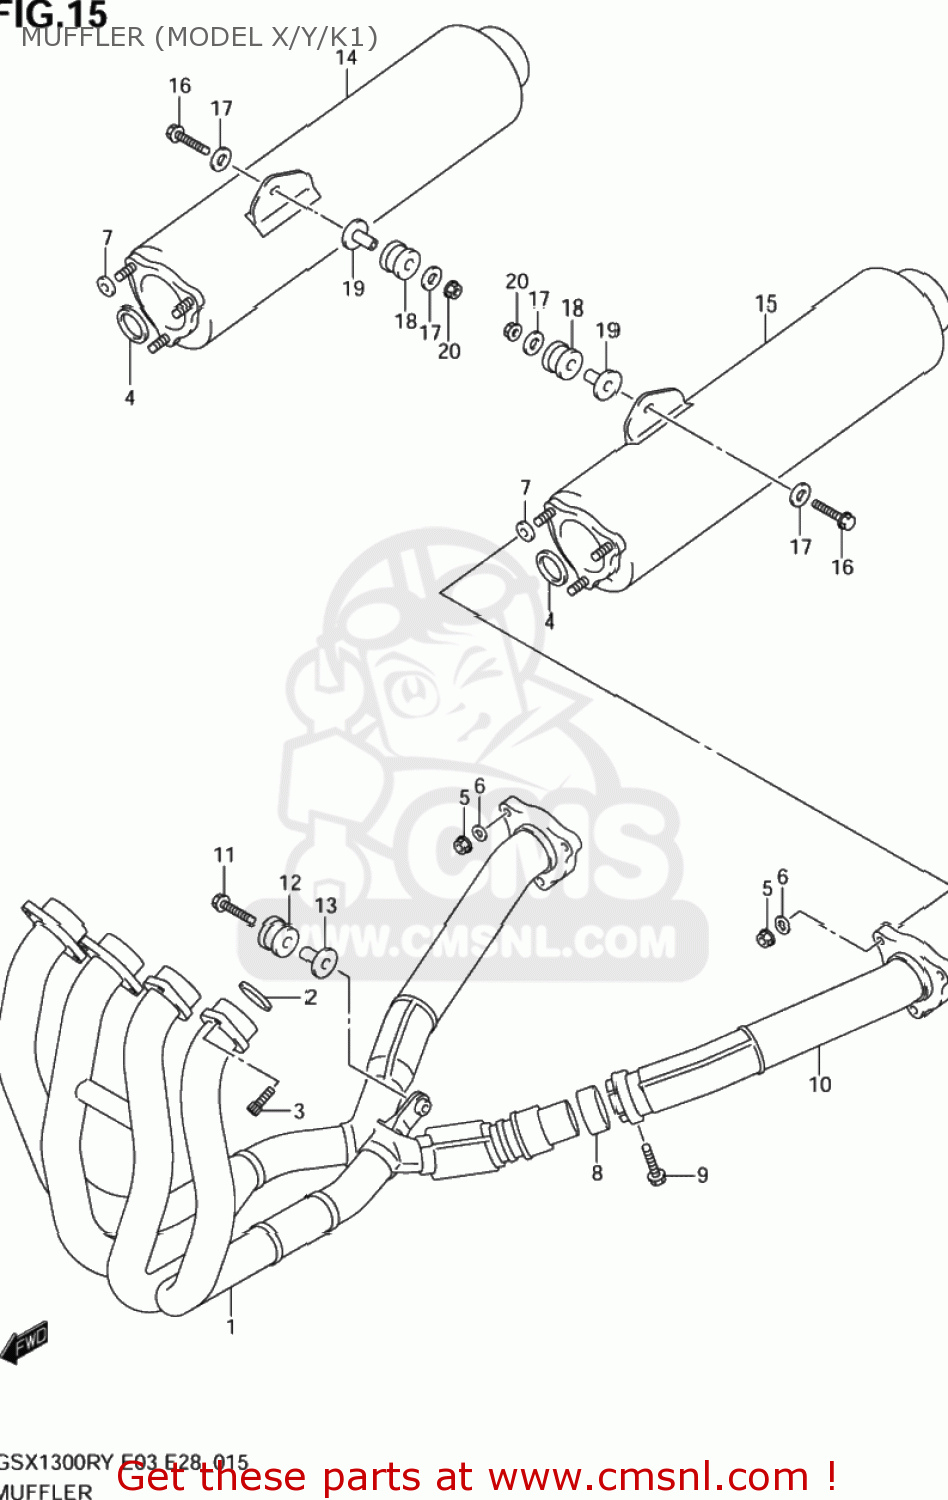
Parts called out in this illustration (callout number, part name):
1	EXHAUST
2	GASKET,EXHAUST PIPE (NAS)
3	BOLT
4	GASKET,MUFFLER JOINT
5	NUT
6	WASHER(8.5X18X1.6)
7	O RING(D:1.9,ID:7.8)
8	CONNECTOR,MUFFLER
9	BOLT
10	PIPE,JOINT,L
11	BOLT 8X45
12	CUSHION
13	SPACER(8.6X12X24.2)
14	BODY,MUFFLER,R
15	BODY,MUFFLER,L
16	BOLT
17	WASHER(8.5X28X1.6)
18	CUSHION
19	SPACER(8.6X12X27.1)
20	NUT
